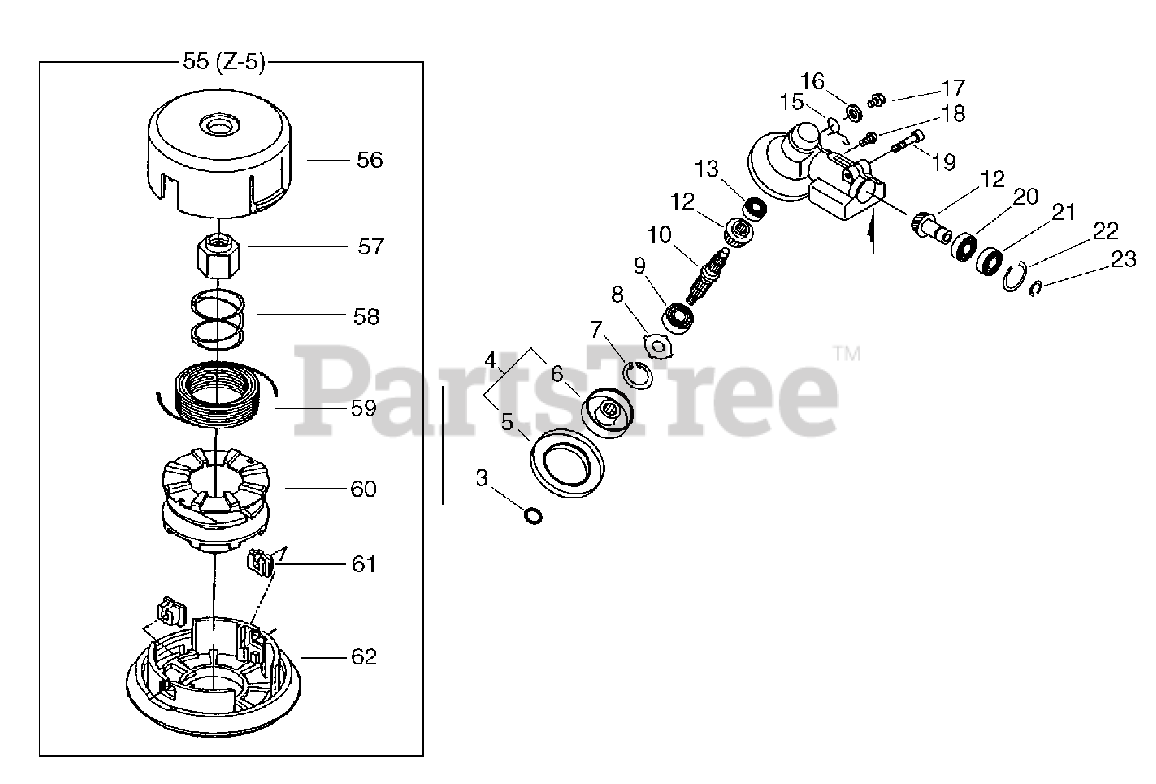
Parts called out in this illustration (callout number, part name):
3	O-RING 12 MM
4	PLATE, ADAPTER - UPPER
4	ADAPTOR PLATE SET
4	RETAINER ASSY, BLADE
5	PLATE, ADAPTOR - LOWER
6	PLATE, ADAPTOR - UPPER
6	RETAINER, BLADE
7	RING, SNAP Ø32
9	BEARING, BALL 6201
10	SHAFT, GEAR
12	GEAR SET
13	BEARING, BALL 629
15	SPRING, TORSION
16	WASHER 8.5×18×0.8T
17	BOLT 8×6
17	BOLT M8×8
18	SCREW 5×10
19	BOLT 6×30
20	BEARING, BALL 6001
21	BEARING, BALL 6001
21	BEARING, BALL 6001Z
22	RING, SNAP 28
23	RING, RETAINING - 12
40	LABEL - CAUTION
40	TRIMMER HEAD
41	REEL, ROPE
41	WASHER 24
42	REEL, ROPE
42	EYELET
43	EYELET
43	SPOOL
43	HOUSING
44	LINE, TRIMMER
44	NUT
45	SPRING
46	SPRING
46	KNOB, TAP
47	COVER
47	SPOOL
48	NUT
48	LINE, TRIMMER
48	CORD, NYLON
49	NUT
49	COVER
50	SCREW 6×10
55	TRIMMER HEAD, Z-5 M10L
56	HOUSING
59	CORD, NYLON
